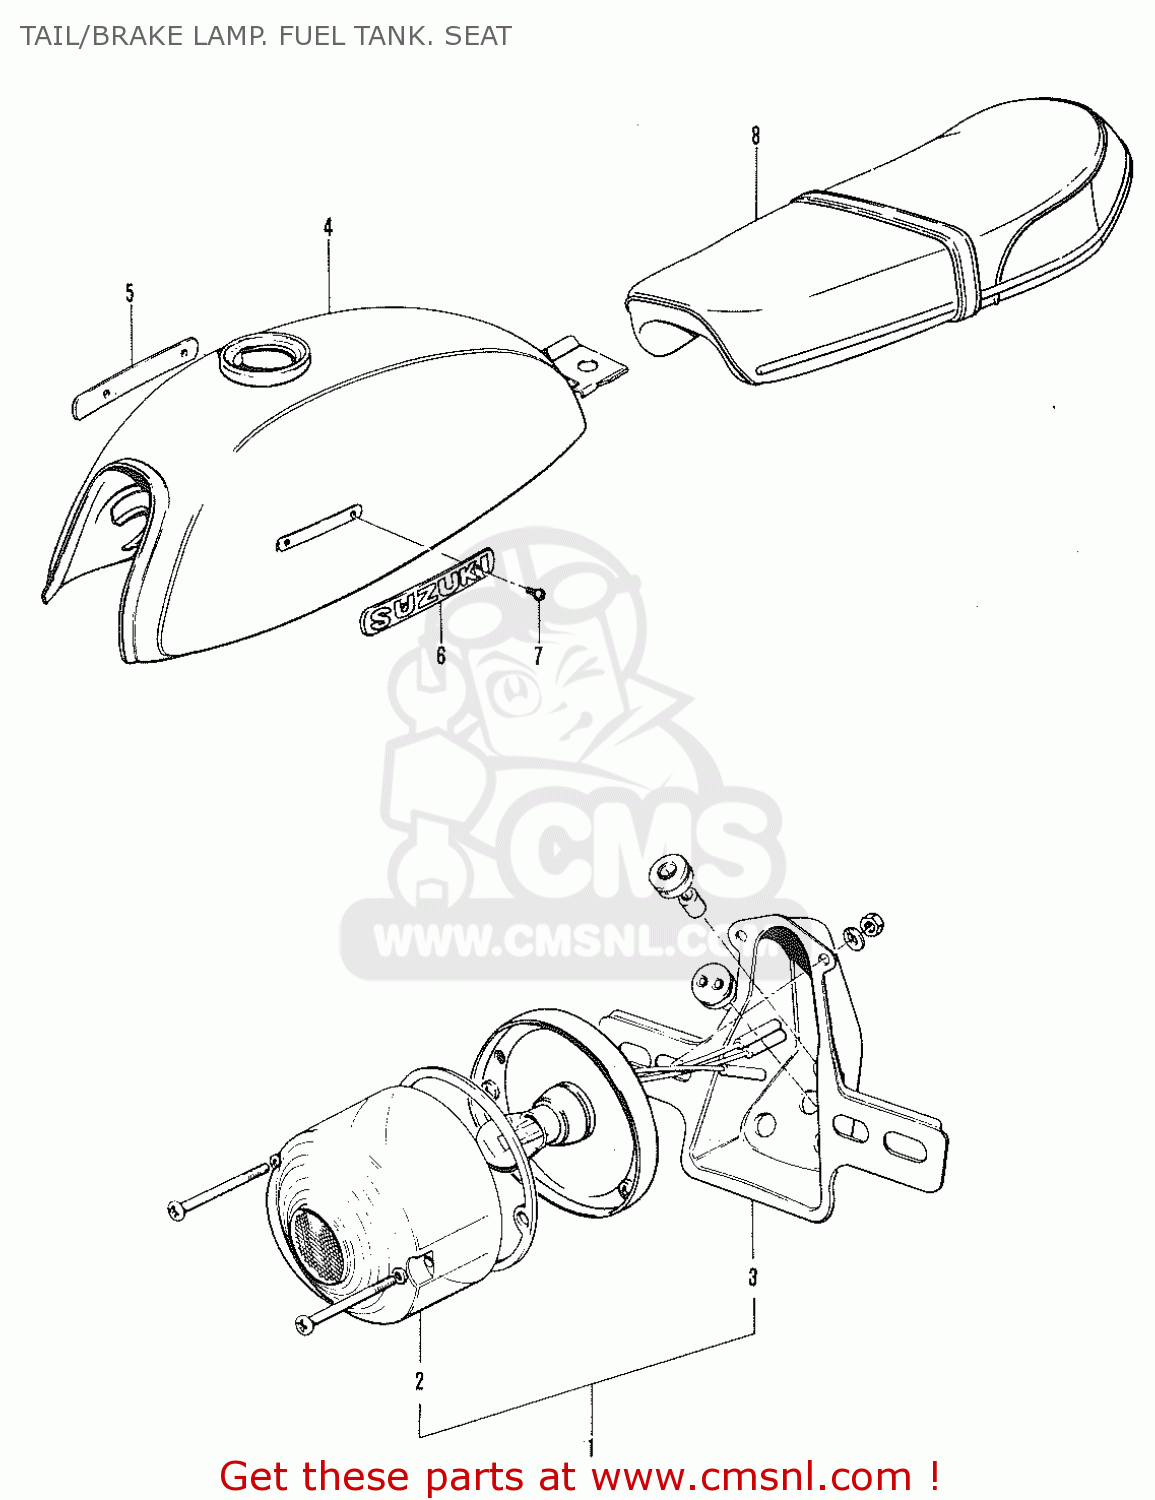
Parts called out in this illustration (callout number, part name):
1	TAIL/BRAKE LAMP ASS'Y
2	LENS,RR COMBINATION LAMP
3	BRACKET
4	TANK ASSEMBLY,FUEL
5	EMBLEM
6	EMBLEM,FUEL TANK
7	screw
8	SEAT ASSEMBLY
